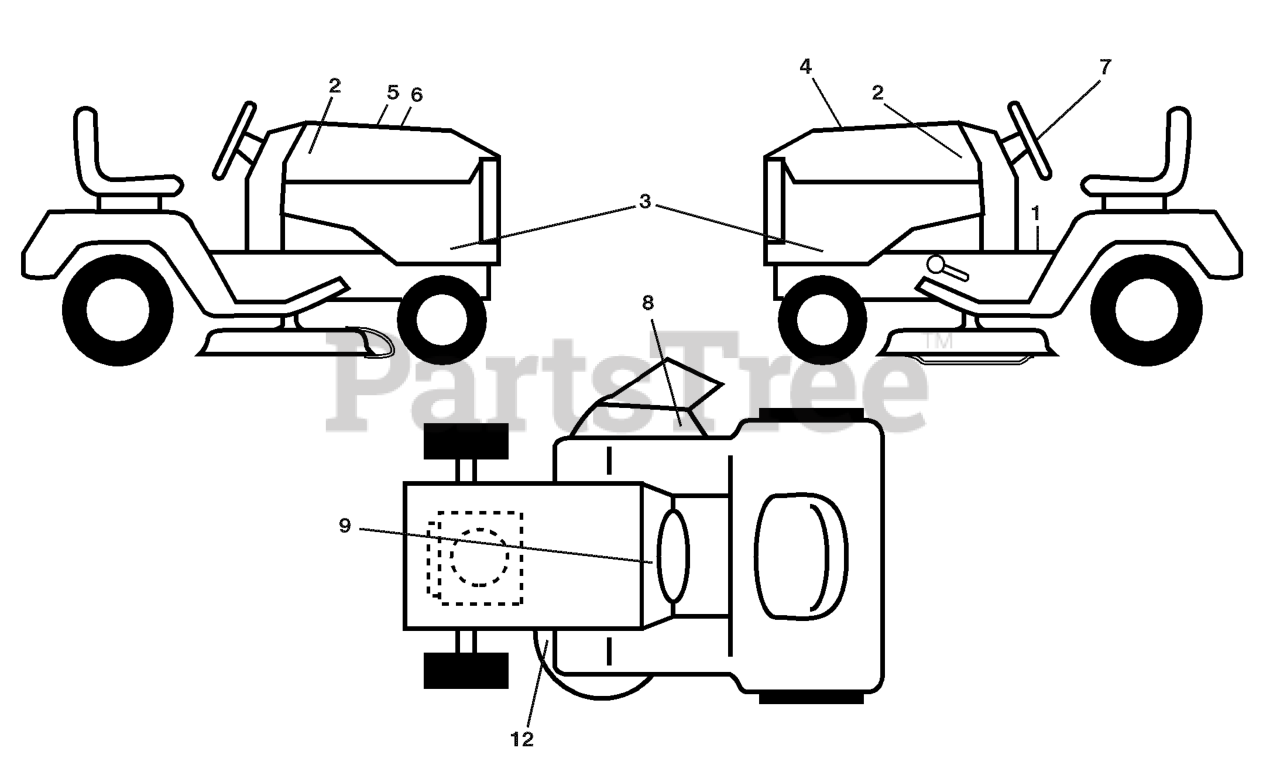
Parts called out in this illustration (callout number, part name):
1	DECAL.FENDER.WARNING.ENG
2	DECAL.HOOD.LOGO.HUSQVARNA
3	DECAL, PANEL SIDE
5	DECAL HOOD CUST. RESP.
6	Decal, Replacement
7	DECAL.WHEEL.STRG.LGN.H
8	DECAL.WARN.KEEP.HAND.AWAY
9	DECAL BTRY SYMBOLS
12	DECAL V BELT SCHEMATIC
12	DECAL.BYPASS.FENDER.CRD.LT.YT
12	PAD.FOOTREST.LH.HUSQ.T
12	PAD.FTRST.RH.PCH.HUSQ.
12	Manual, Owner's
